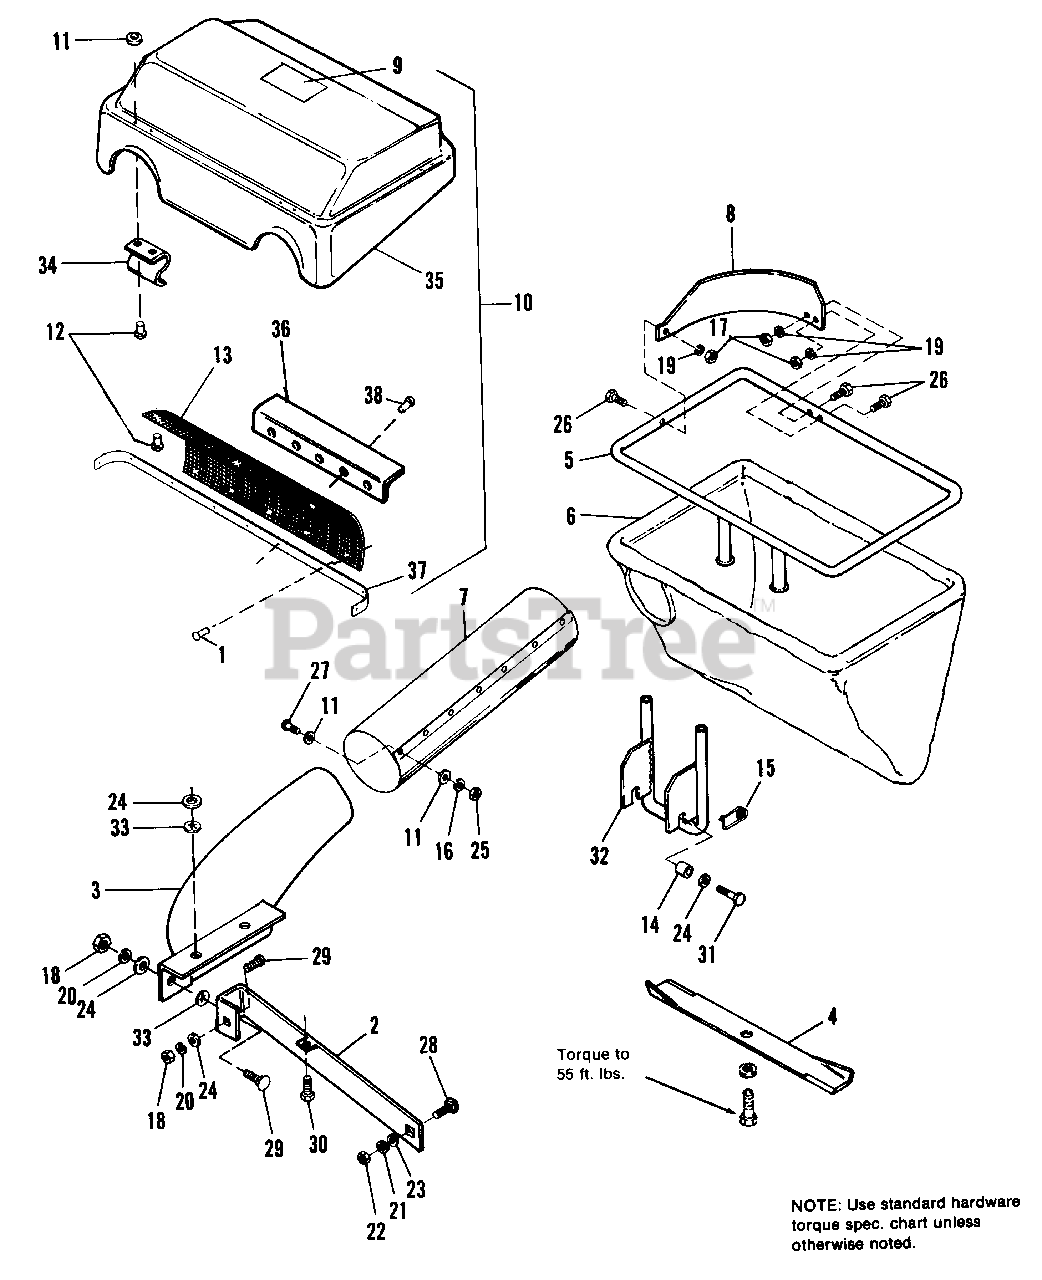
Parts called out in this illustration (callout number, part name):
1	RIVET, Pop, 3/16 x 21/32
2	BAFFLE ASSY., Discharge
3	ADAPTOR, Mower
4	BLADE
5	FRAME ASSY., Bag
7	TUBE, Discharge
8	DEFLECTOR
9	DECAL, Warning
10	COVER ASSY.
11	WASHER, Rivet, 3/16
12	RIVET, Pop, 3/16 x 13/32
15	PIN, Clip, Safety
16	LOCKWASHER, #10
17	NUT, Hex, 1/4-20
18	NUT, Hex, 3/8-16
19	LOCKWASHER, 1/4
20	LOCKWASHER, 3/8
21	LOCKWASHER, 5/16
22	NUT, Hex, 5/16-18
23	WASHER, 1/4
24	WASHER, 3/8
25	NUT, Hex, #10-32
26	CAPSCREW, Hex, 1/4-20 x 1-1/4
27	SCREW, Phillips #10-32 x 3/8
28	BOLT, Carriage, 5/16-18 x 3/4
29	BOLT, Carriage, 3/8-16 x 3/4
30	SCREW, Hex, Taptite, 5/16-18 x 1
31	CAPSCREW, Hex, 3/8-16 x 1-1/4
32	SUPPORT ASSY., Frame
33	NUT, Push On
34	CLIP, Cover
36	ANGLE, Screen
38	RIVET, Tubular, 3/16 x 3/8
